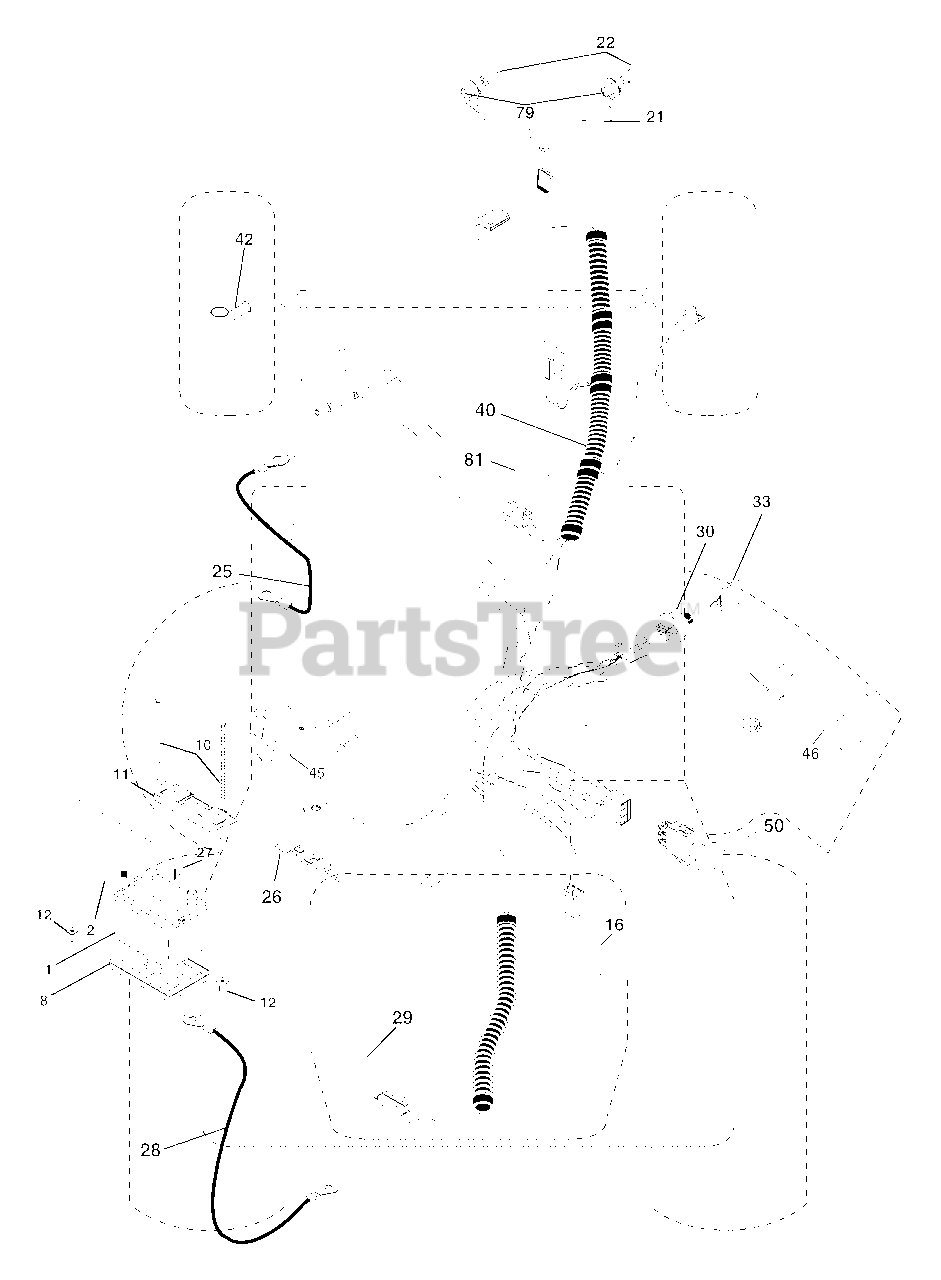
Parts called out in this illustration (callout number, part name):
1	Battery
2	Bolt Hex Head 1/4-20 x 3/4
8	Tray, Battery
10	Bolt, Battery Front 1/4-20 x 7.5 Zinc
11	Holddown Battery Front Mount
12	Nut, Push Nylon 1.4" Battery Front
16	Switch Interlock
21	Harness Socket Light w/4152J
22	Bulb Light
25	Cable, Battery
27	Nut Keps Hex 1/4-20
28	Cable, Ground
29	Switch, Plunger NC Gray
30	Switch, Ign
40	Harness Ign.
42	Cover, Terminal Red
46	Hourmeter Snap-In
50	Switch, PTO
79	Bulbholder Asm
81	Relay Asm.
